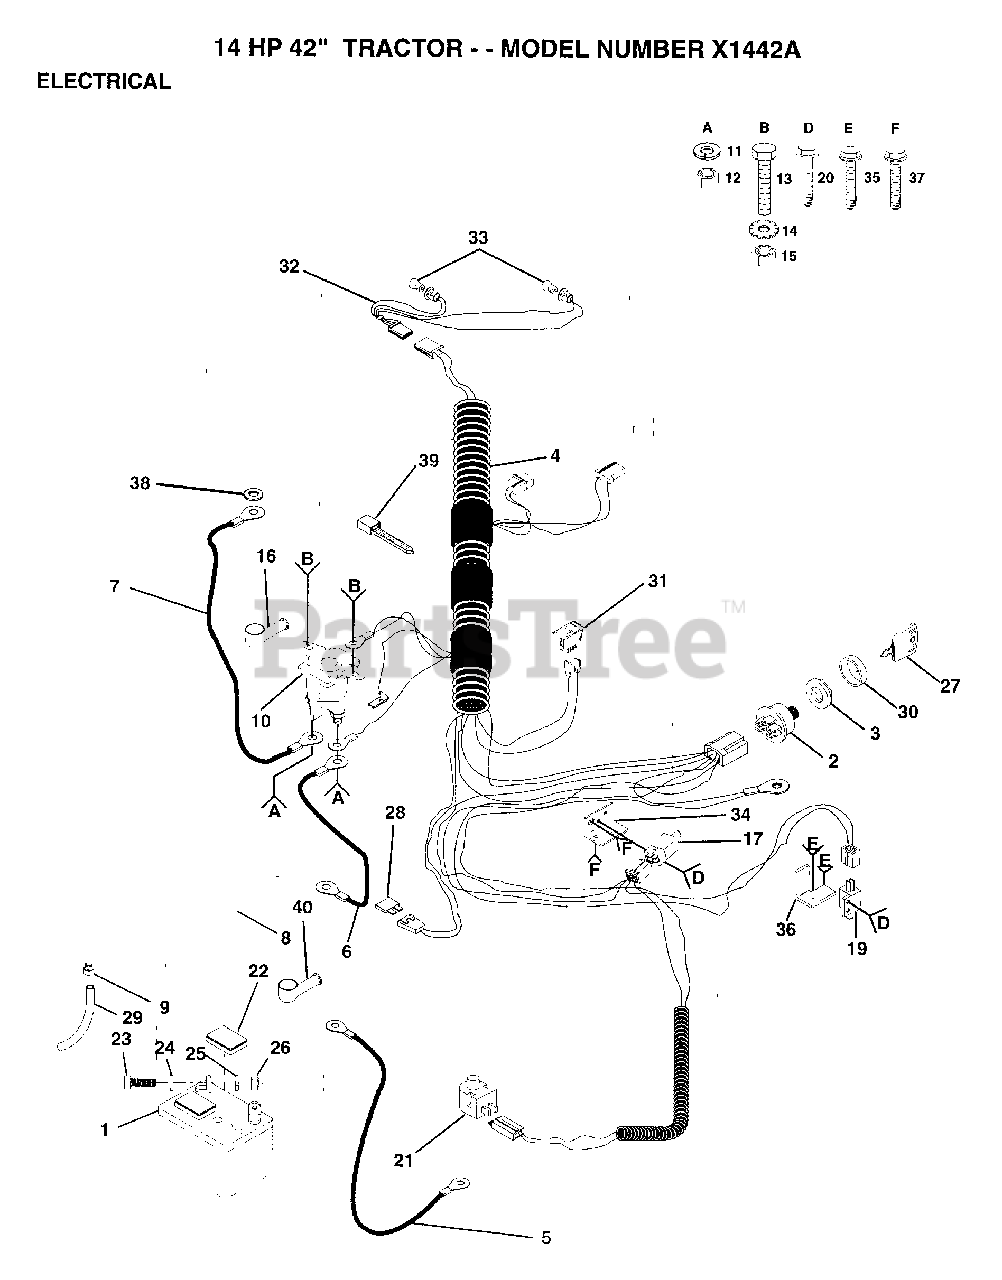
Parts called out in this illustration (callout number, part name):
3	NUT IGNITION
4	HARNESS.IGN.B&S
5	CABLE T
7	CABLE-BATTERY T
8	BTRY CASE W/O LID
9	HOSE CLAMP T
12	NUT
13	BOLT
15	NUT
17	SWITCH INTERLOCKT
19	SWITCH-INTER. GT
20	SCREW
21	SWITCH SEAT
22	"CAP,BATTERY "
23	BOLT LT
24	WASHER
25	LOCKWASHER
27	KEY
28	FUSE HYT
29	TUBE T
31	SWITCH LT
34	BRACKET LT
35	SCREW
36	SWITCH BRACKET
37	SCREW
38	LOCKWASHER
39	WIRE TIE
